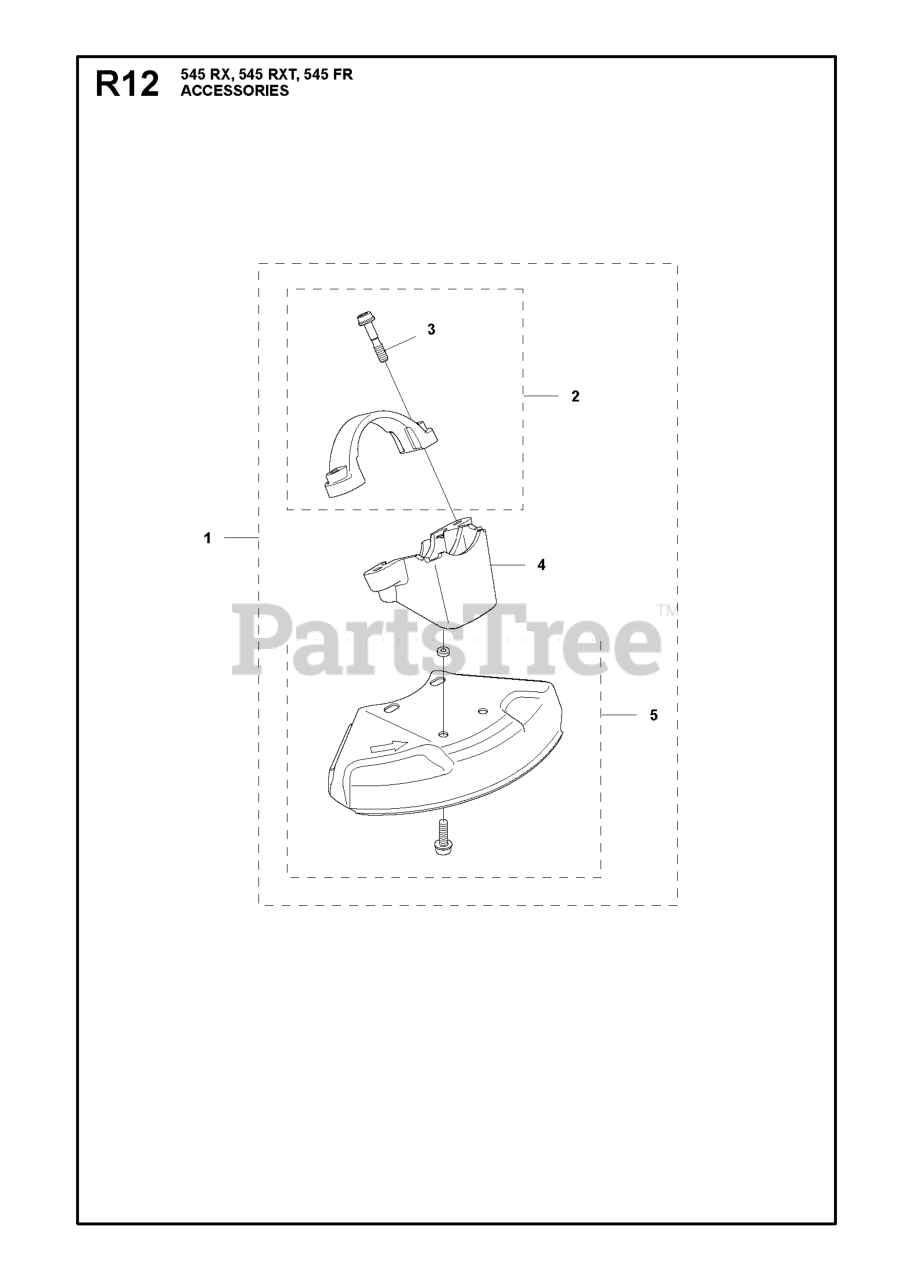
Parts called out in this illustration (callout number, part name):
1	TRIMMER GUARD ASSY
2	CLAMP
3	SCREW IHSCFMO
5	BLADE GUARD
